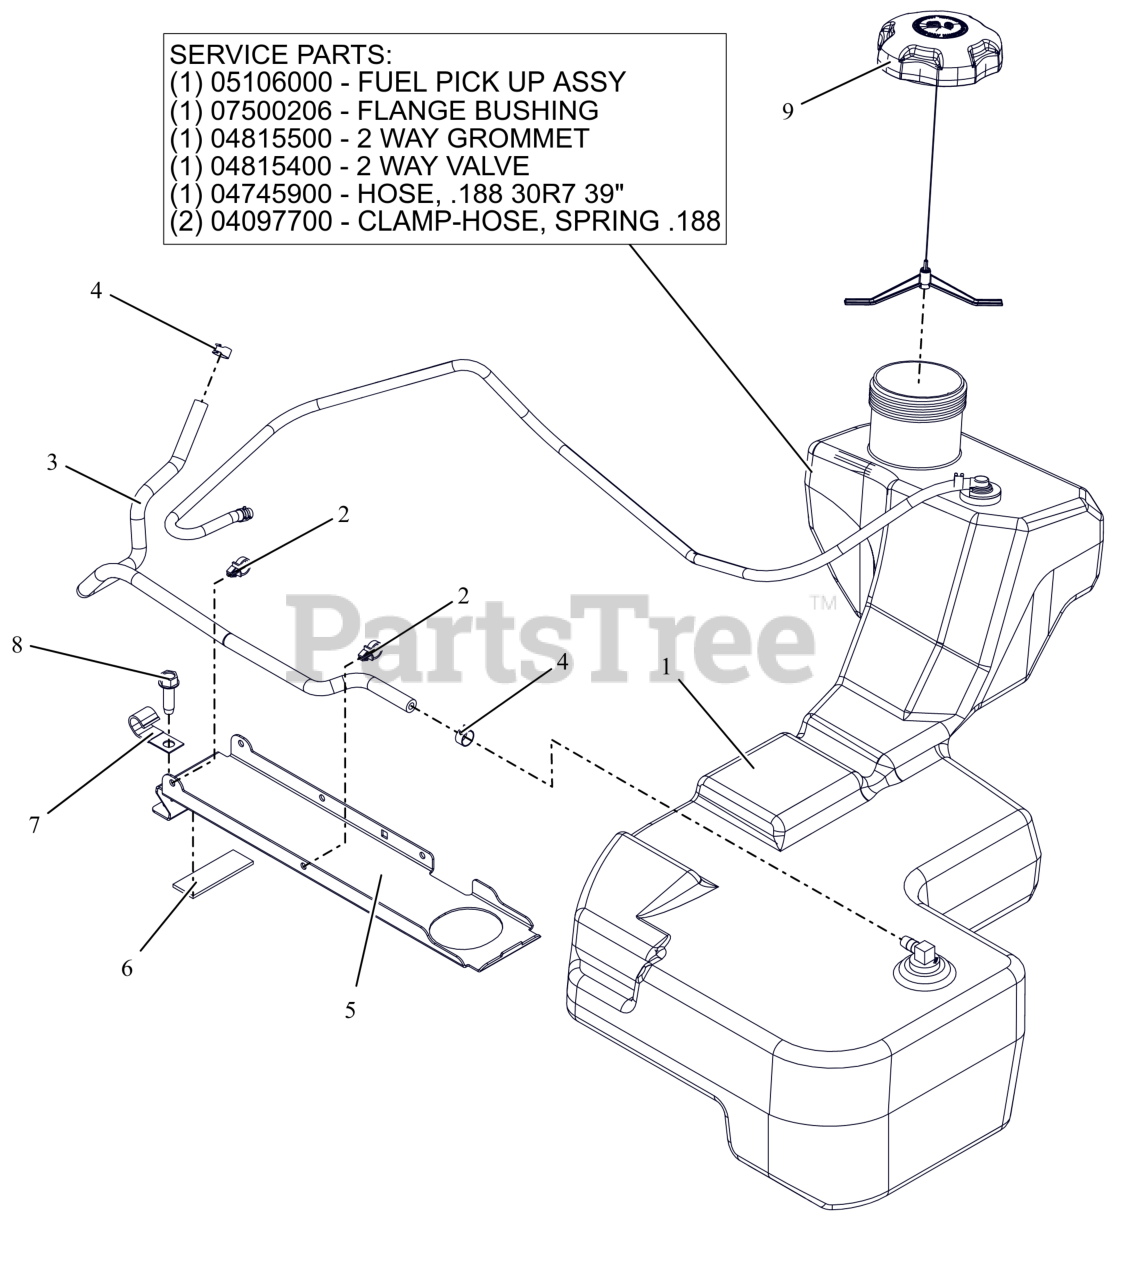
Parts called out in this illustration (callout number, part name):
1	ASM, FUEL TANK-HD
1	ASM, HD FUEL PICK-UP
1	BSHG-FLG .375X1.062X.625 NITR
1	GROMMET, 2-WAY
1	VALVE, 2-WAY
1	HOSE, .188 30R7 BULK
1	CLAMP-HOSE, SPRING .188
2	ROUTING CLIP (1/2" ID)
3	HOSE, .25 LOW-PERM BULK GAS
4	CLAMP, FUEL LINE
5	BRKT, FUEL TANK HOLD DOWN
6	PAD,RBR 1.0"X3.0" W/ADHESIVE
7	J-CLAMP
8	SCR,TAP .375-16X1.25HWH TR ZCC
9	CAP, FUEL - 3.50 RATCHET INLET VENT
